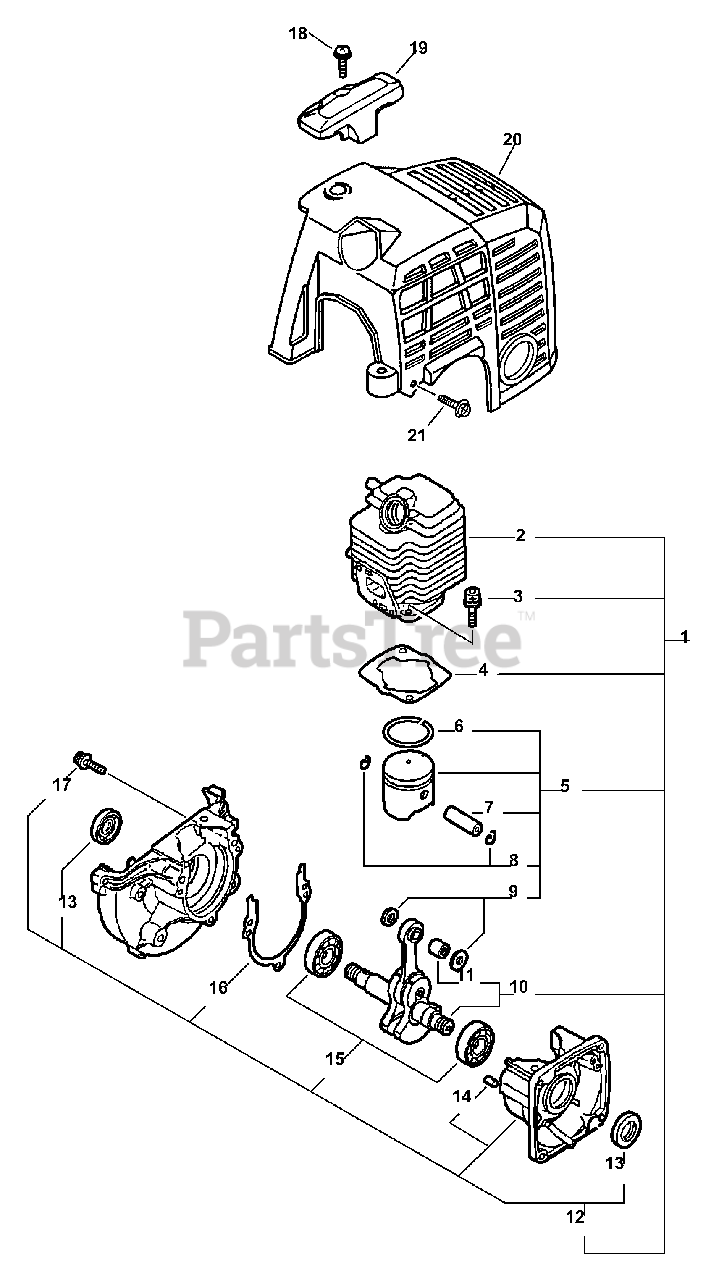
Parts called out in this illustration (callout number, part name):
1	SHORT BLOCK -- SB1026
2	CYLINDER
3	SCREW - 5X22
4	GASKET, CYLINDER
5	PISTON KIT
6	RING, PISTON
7	PIN, PISTON
8	RING, RETAINING
9	SPACER, PISTON
10	CRANKSHAFT ASSY
11	BEARING, NEEDLE
12	CRANKCASE KIT
13	SEAL, OIL
14	PIN - LOCATING
15	BEARING, BALL - 6201
16	GASKET, CRANKCASE
17	SCREW - 5X28
18	SCREW - 5X16
19	GUARD - TOP
20	COVER, ENGINE
21	SCREW - 4X16
